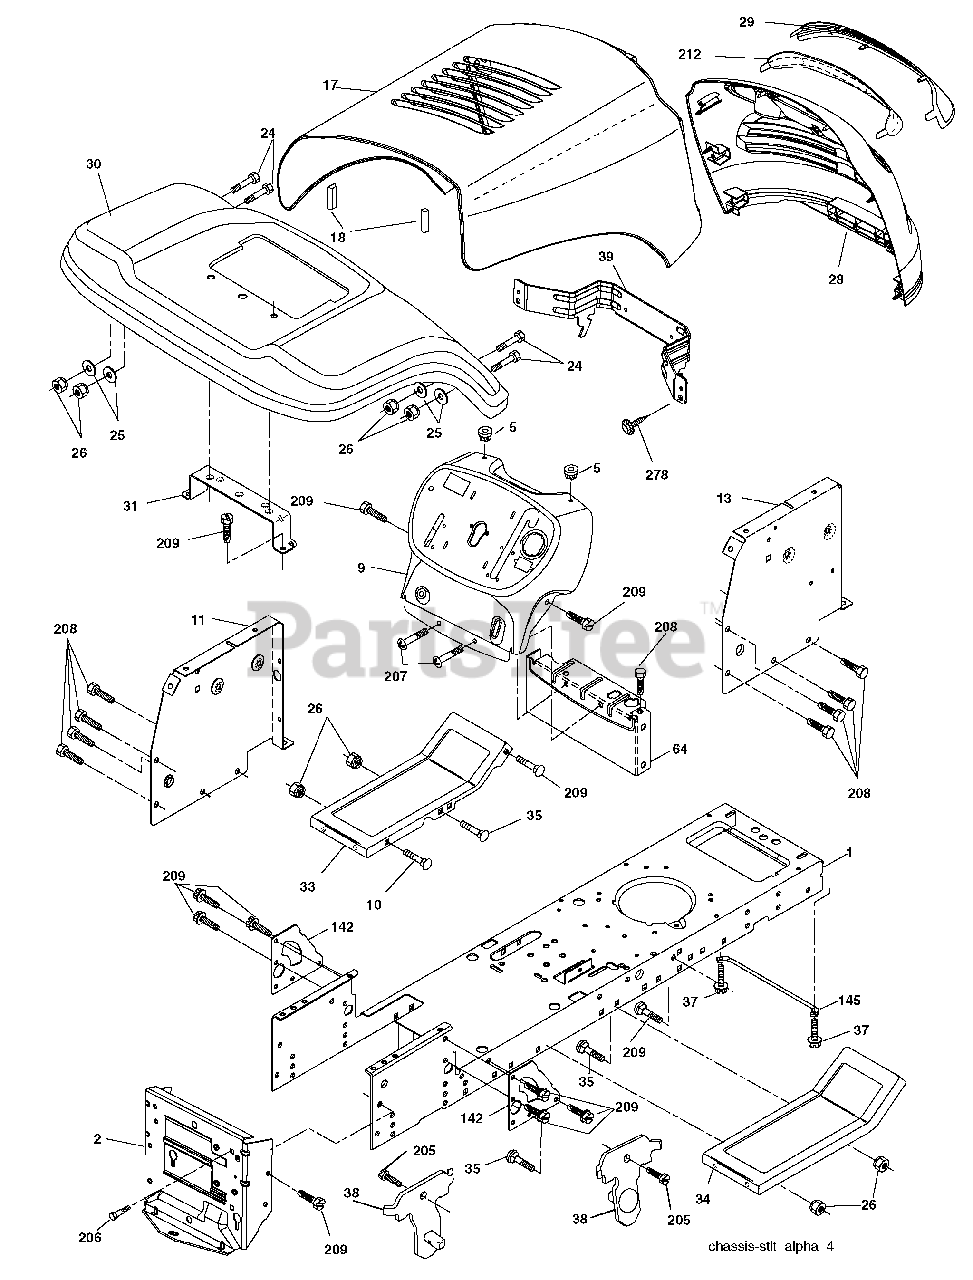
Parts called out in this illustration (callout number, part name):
1	Chassis
2	Drawbar, Stretch
5	Bumper, Hood/Dash
9	Dash
10	Bolt, Carriage 3/8-16 x 1
11	Panel Dash LH
13	Panel Slkscr Dash RH
17	Hood
18	Bumper Hood
24	Bolt Fin Hex 3/8-16 unc x 1 Gr. 5
25	Washer 13/32 x 13/16 x 12 Ga.
26	Nut Lock Hex w/Ins 3/8-16 unc
28	Grille/Lens Asm.
29	Lens Grille Bar
30	Fender
31	Bracket Fender Repl 109873X
33	Footrest Pnt LH
34	Footrest Pnt RH
35	Bolt Rdhd Sht Sqnk 3/8-16 x 3/4
37	Screw Thdrol 5/16-18 x 1/2 TYT
38	Bracket Asm. Pivot Mower
39	Bracket Pivot
64	Dash Lower
142	Plate Reinforcement
145	Rod Pivot Chassis/Hood
205	Screw Thdrol 3/8-16 x 1/2
206	Bolt Shoulder 5/16-18
207	Screw 5/16-18 x 1/2
208	Screw Thdrol 3/8-16 x 1/2
209	Screw Hex Wsh Thdrol 3/8-16
212	Insert Lens Reflect
278	Screw #10 X 0.750 BOS Thread
278	Plug Button Blk 359 Dia Choke
278	Plug Dome Plastic
